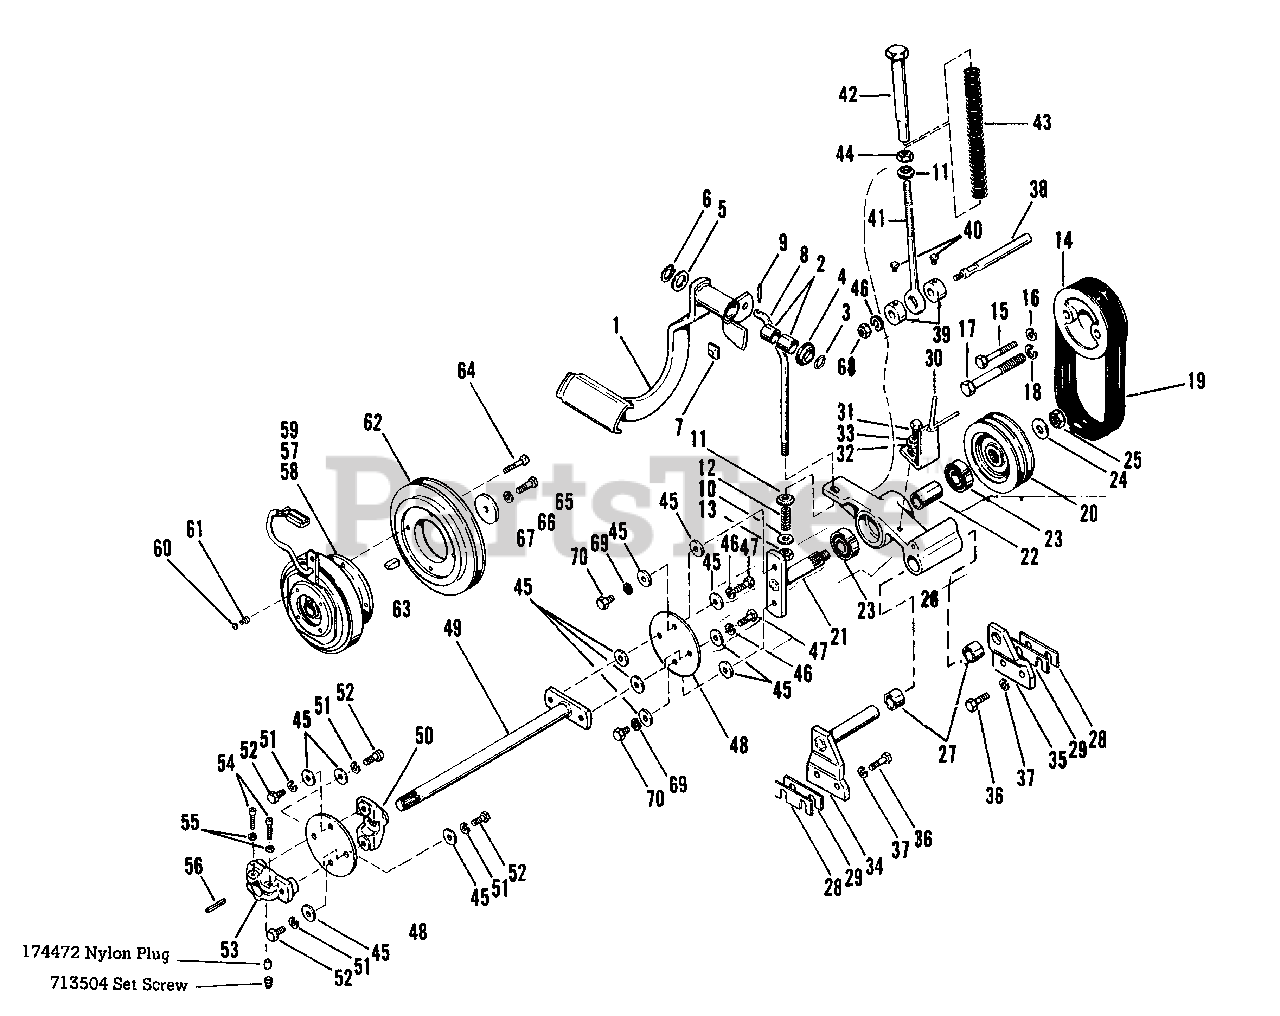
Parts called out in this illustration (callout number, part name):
1	Lever Assembly
2	Bearing Sleeve
3	Retaining Ring
6	Retaining Ring
8	Clutch Rod
9	Cotter Pin
10	Plain Washer, 3/8"
11	Clutch Spacer
13	Hex Nut, Full, Lock, 3/8"-16
14	Input Pulley
15	Hex Capscrew, 3/8"-16 x 2-3/4" lg.
16	Lock Washer, 3/8"
17	Hex Capscrew, 7/16"-14 x 4 1/2" lg.
18	Lock Washer, 7/16"
19	Matched "V" Belts
20	Input Pulley
21	Shaft Assembly
24	Plain Washer
25	Jam Nut, Lock, 1/2"-13
26	Pivot Arm
27	Bearing Sleeve
30	Belt Stop
31	Hex Capscrew, 5/16"-18 x 3/4" lg.
32	Plain Washer, 5/16"
33	Lock Washer, 5/16"
34	Support Assembly
35	Support Assembly
36	Hex Capscrew, 3/8"-16 x 1-1/4" lg.
37	Lock Washer, 3/8"
38	Pivot Shaft
40	Set Screw, 5/16"-18 x 5/16" lg.
42	Tube Assembly
44	Jam Nut, Lock, 3/8"-16
46	Lock Washer, 3/8"
47	Hex Capscrew, 3/8"-16 x 7/8" lg.
49	Shaft Assembly
51	Lock Washer, 3/8"
52	Hex Capscrew, 3/8"-16 x 1" lg.
53	Clamp Yoke
54	Socket Hd. Screw, 5/16"-18 x 1" lg.
55	Lock Washer, 5/16"
57	Electric Clutch
60	Lock Washer No. 10
61	Socket Hd. Screw No. 10-32 x 1/2" lg.
64	Self Tapping Screw, 5/16"-18 x 1-1/2" lg.
65	Hex Capscrew, 3/8"-24 x 1" lg.
66	Lock Washer, 3/8"
68	Hex Nut, Full, 3/8"-16
69	Shake Proof, Lock Washer 3/8"
70	Hex Capscrew, 3/8"-16 x 7/8" lg.
